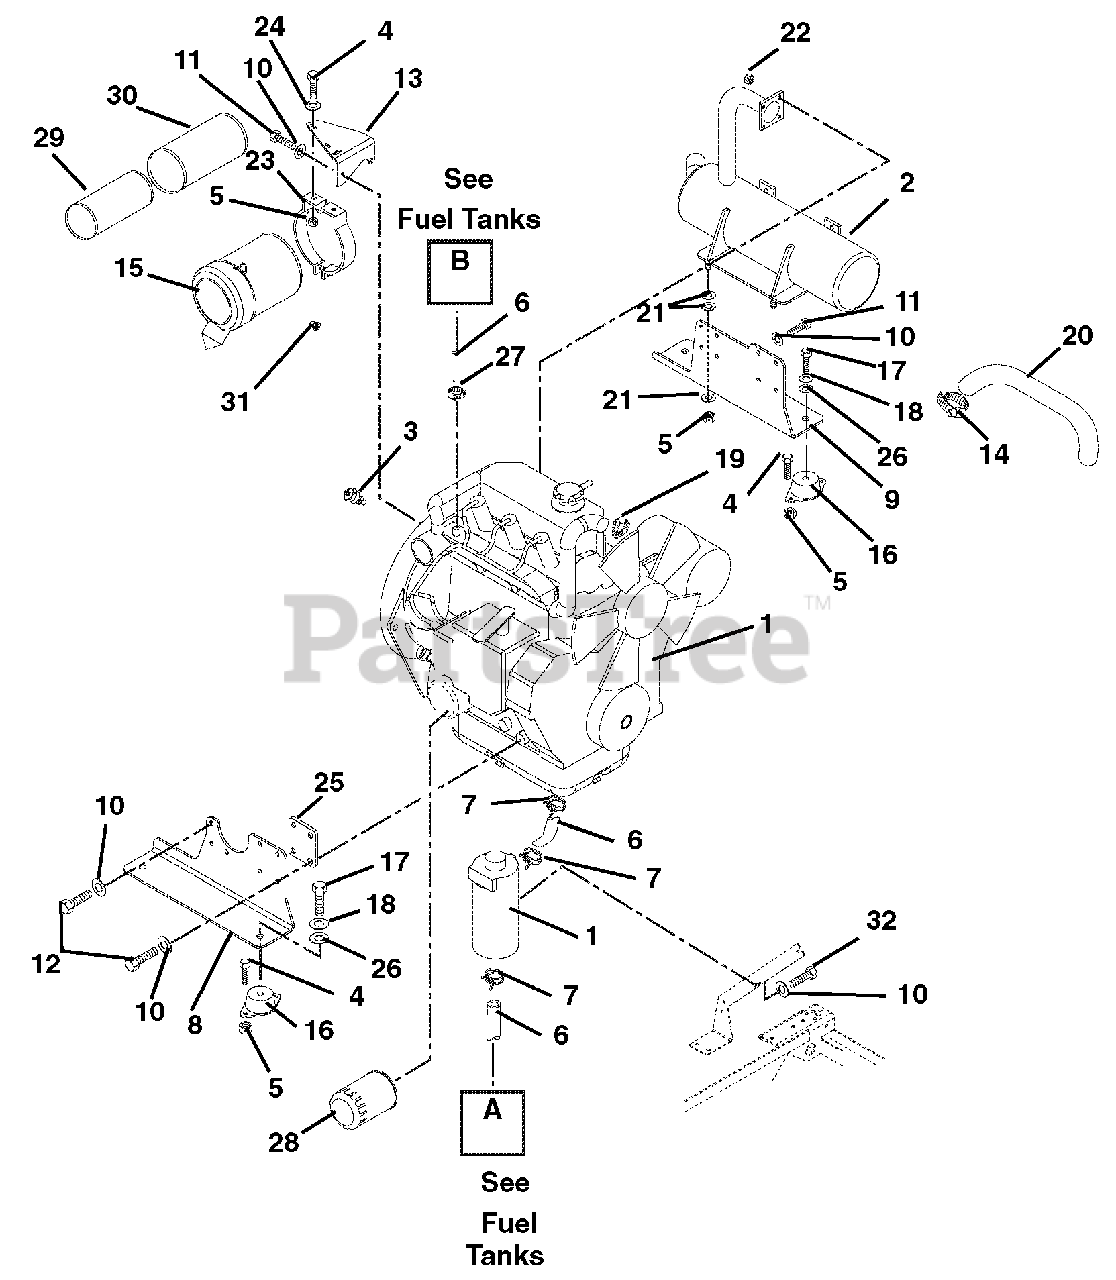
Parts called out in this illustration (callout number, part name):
1	ENGINE, 27HP DIESEL (DAIHATSU)
2	MUFFLER
3	SENDER, TEMPERATURE
4	@BLT-HEX .31-18X.75 GR5 YWZC
5	@NUT-LK-TOP-FLG .31-18 YWZC
6	HOSE,5/16 ID
7	CLAMP, HOSE WIRE .520/.550
8	MOUNT, ENGINE RH (DIESEL)
9	MOUNT, ENGINE LH (DIESEL)
10	@WSHR-LK .31X.078 REG YWZC
11	@BLT-HEX M8-1.25X20 YWZC
12	BLT, HEX M8-1.25X25 GR8.8YWZC
13	BRKT, AIR CLEANER - BLACK
14	CLAMP, HOSE #32 (1.56/2.50)
15	AIR CLEANER ASSEMBLY
16	MOUNT, ENGINE, VIBRATION ISO
17	BLT-HEX .50-20X1.00 GR5 YWZC
18	@WSHR-LK .50X.125 REG YWZC
19	CLAMP-HOSE 1.50X.81X1.42
20	HOSE, AIR CLEANER
21	@WSHR-FL-STL.38X.875X.083 YWZC
22	NUT-LK-TOP M8-1.25 YWZC
23	BRACKET, AIR CLEANER MOUNT
24	@WSHR-FL-STL.38X.875X.083 YWZC
25	SPACER, ENGINE MTG (DIESEL)
26	@WSHR-FL-STL.531X1.06X.095YWZC
27	CLAMP, HOSE, IDEAL 6202 SIZE 4
28	FILTER, OIL
29	ELEMENT, INNER SAFETY
30	ELEMENT, OUTER PRIMARY
31	PLUG, PIPE .125-27 SLHD YWZC
32	@BLT-HEX M6-1X16 YWZC
